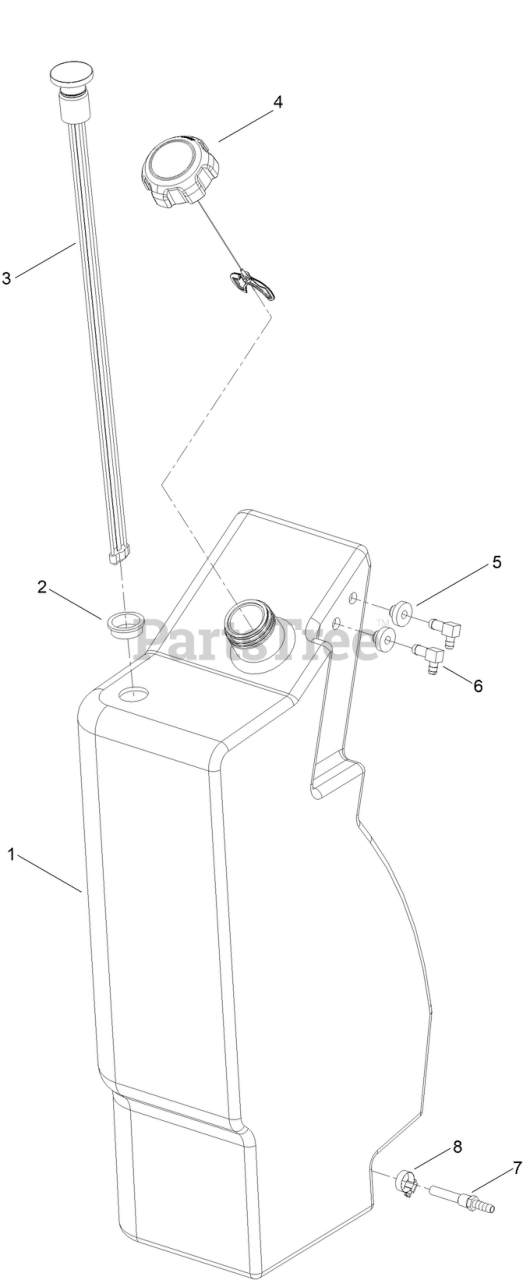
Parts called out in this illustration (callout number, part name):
1	TANK-DEISEL
2	GROMMET
3	GAUGE-LEVEL, FUEL
4	CAP-DIESEL
5	BUSHING
6	FITTING-ELBOW, 90 DEG
7	FITTING-STRAINER
8	CLAMP-HOSE
